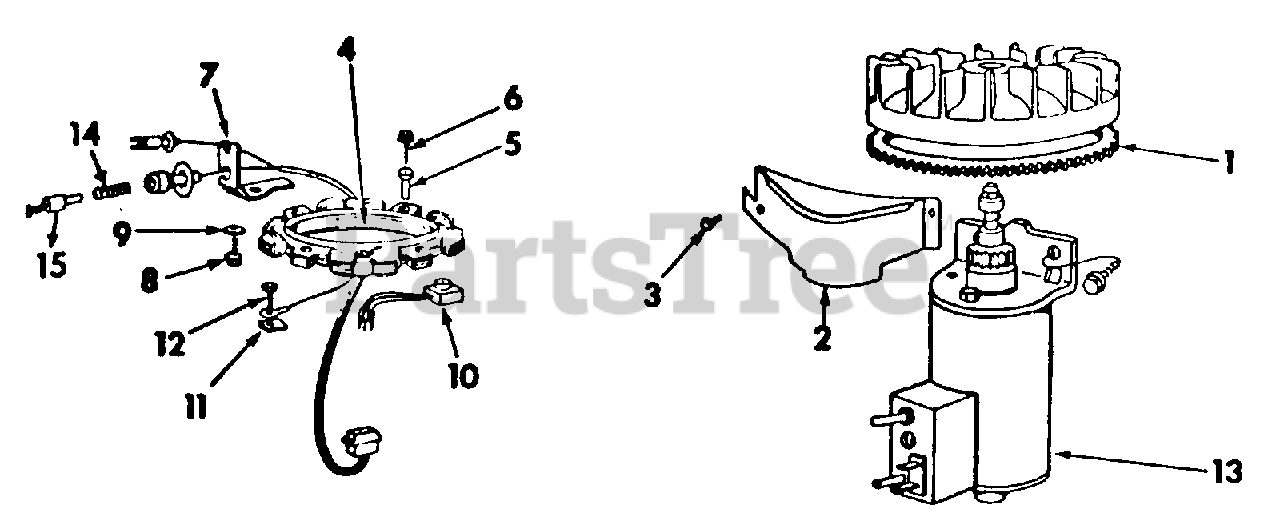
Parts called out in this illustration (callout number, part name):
1	Gear, Flywheel Ring
2	Guard, Ring Gear
3	Screw, Guard Mounting
4	Stator w/Bracket, Alternator
5	Bushing, Stator
6	Screw, Stator Mounting
7	Bracket, Fuse
8	Screw, Bracket Mounting
9	Washer, Bracket
12	Screw, 8-32 X 3/8 Hex Hd
13	Motor Assy, Starter
14	Spring, Diode
